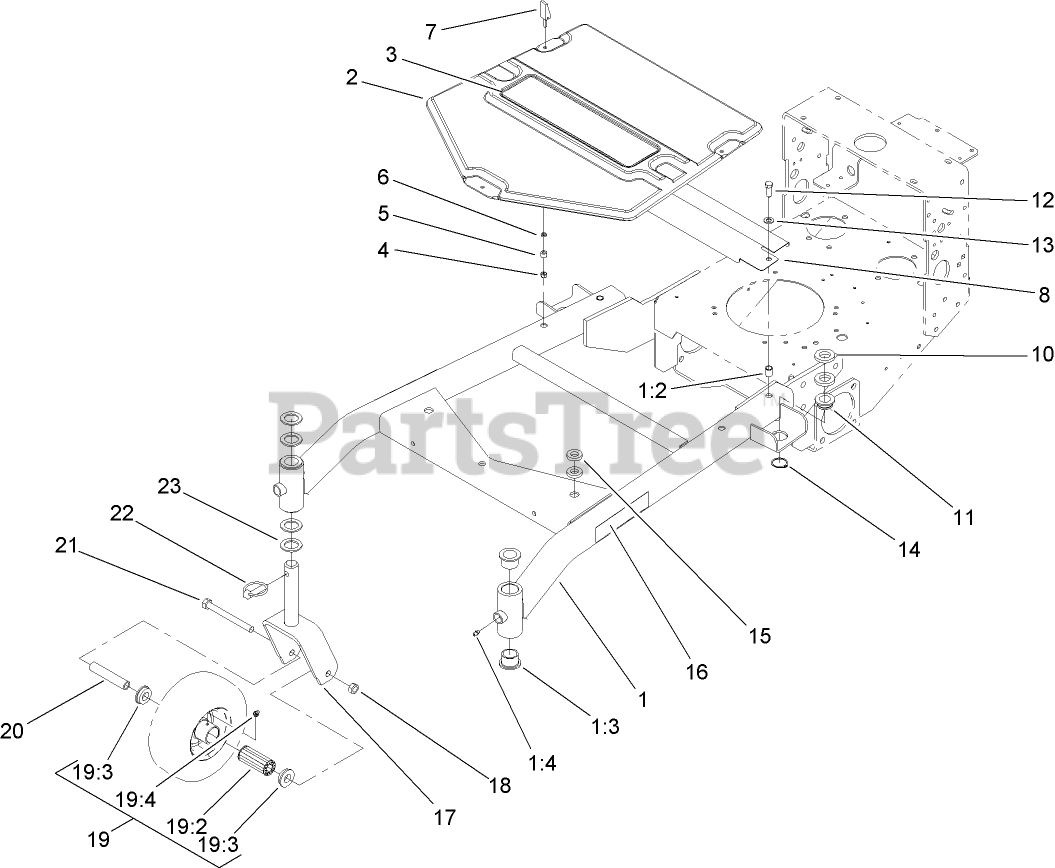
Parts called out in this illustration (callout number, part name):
1	CARRIER FRAME ASM
1:2	INSERT-NUT
1:3	BUSHING
1:4	FITTING-GREASE
2	COVER-FRAME, CARRIER
4	NUT-LOCK, HH
5	BUSHING-LATCH, SWELL
6	WASHER
7	HANDLE-LATCH, SWELL
8	SHIELD-BELT
10	SPACER-SUPPORT, DECK
11	BUSHING-DECK
12	SCREW-HH
13	WASHER-FLAT
14	RING-RETAINING
15	SPACER
16	DECAL-HOC
17	FORK-CASTOR
18	NUT-HEX
19	WHEEL AND TIRE ASM
19:2	BEARING-ROLLER
19:3	BUSHING
19:4	FITTING-GREASE
20	BUSHING-SPANNER
21	SCREW-HH
22	PIN-LYNCH
23	WASHER-THRUST
